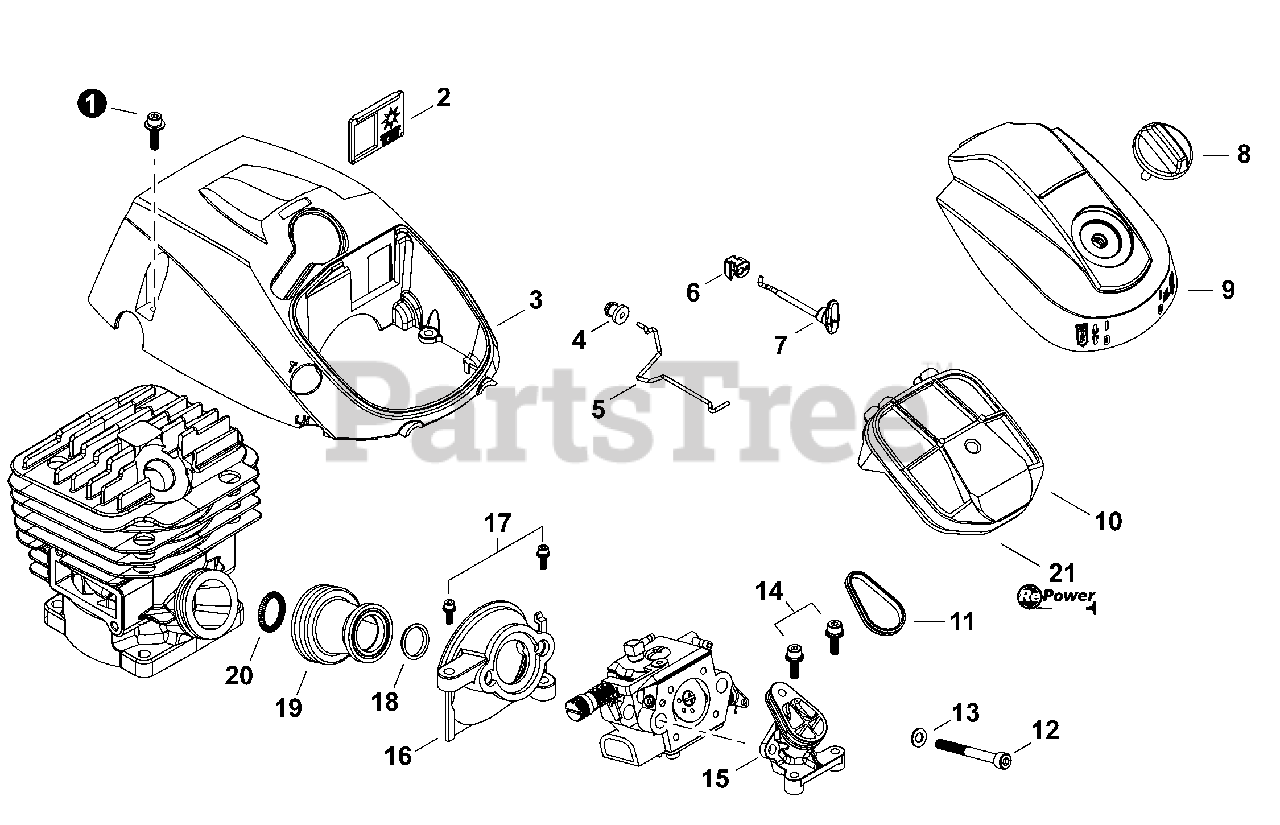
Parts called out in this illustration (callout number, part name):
1	BOLT M4×16
2	PLATE, SHUTTER
3	COVER, ENGINE
4	GROMMET, THROTTLE ROD
5	ROD, THROTTLE
6	GROMMET, CHOKE
7	ROD, CHOKE
8	THUMBSCREW
9	COVER, AIR FILTER
10	AIR FILTER ASSY, FLOCKED
12	BOLT M5×48
13	WASHER, FLAT 5.5×10×0.8
14	BOLT M4×16
15	ADAPTOR, AIR FILTER
16	INSULATOR, INTAKE
17	BOLT M4×16
18	COLLAR 16
19	BELLOWS, INTAKE
20	SPRING, TENSION
21	TUNE-UP KIT - REPOWER
